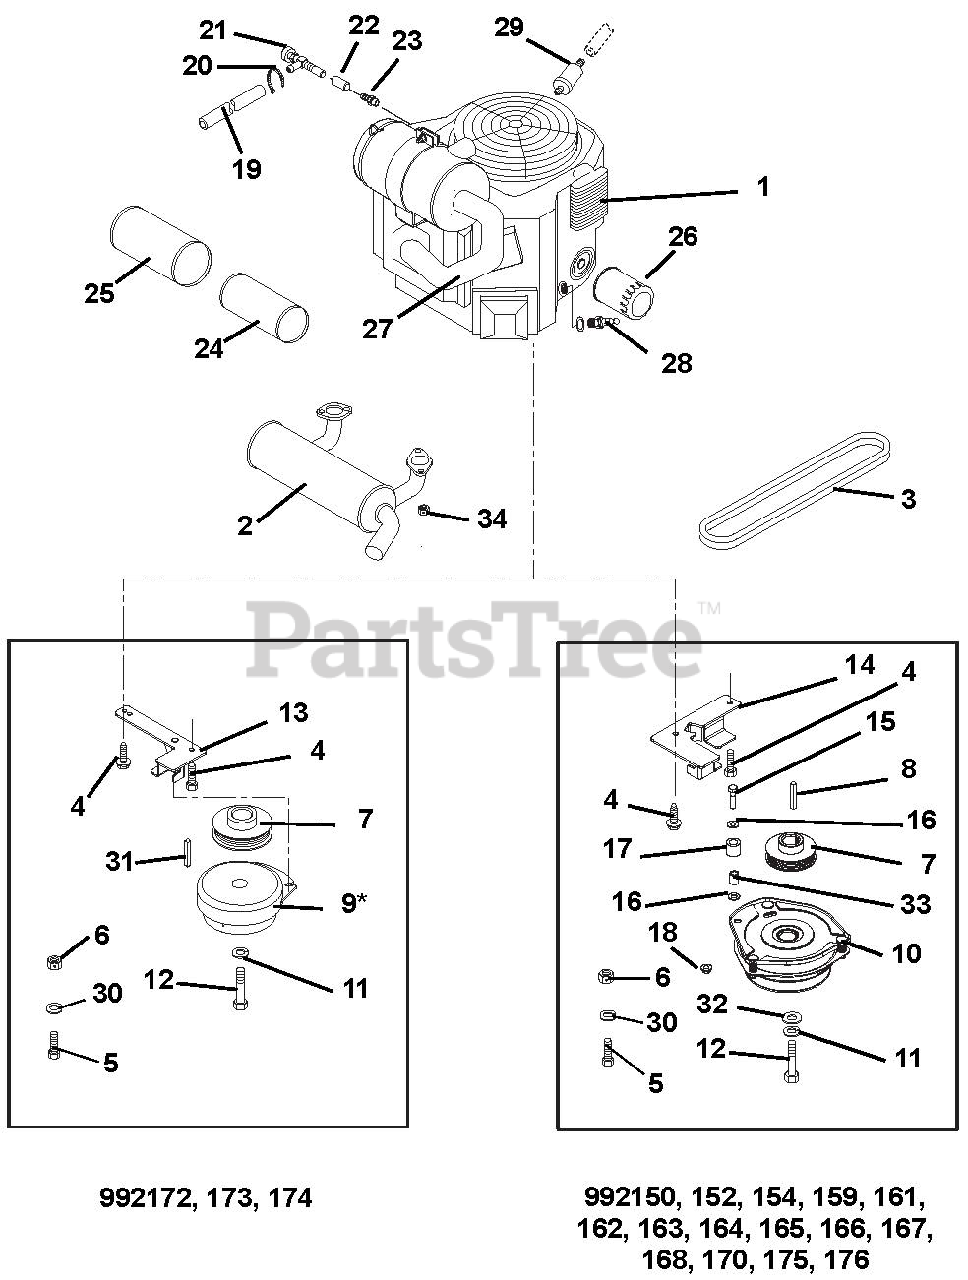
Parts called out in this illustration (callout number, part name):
1	Engine, 26hp Liquid Cooled Kawasaki
1	Engine, 27hp Kohler
1	Engine, 27hp Kawasaki
1	Engine, 25hp Kohler Command
1	Engine, 30hp Kohler Command Pro
1	Engine, 31hp Kawasaki
1	Engine, 27hp Kohler Command
2	Muffler, Kawasaki Vertical
2	Muffler, Kawasaki Liquid Cooled
2	Muffler, Kohler Twin
3	Belt, Poly-V
4	Screw, Tapping Hex Washer Head .38-16 x 1.50
4	Bolt, Hex M8-1.25 x 25 Grade 8
4	Bolt, Hex .38-16 x 1.25 FTH G5 EP30
5	Bolt, Hex .31-18 x 1.75 Grade 5
6	Nut, Locking Top Flange .31-18
7	Sheave, Poly V 1.127 x 3.275
8	Key, Square .25 x 3.50 x .25 SAE
9	Clutch, Electric
10	Clutch, Electric
11	Washer, Locking .44 x .109
12	Bolt, Hex .44-20 x 3.00 Grade 5 YZ EP80
12	Bolt, Hex .44-20 x 1.50 Grade 5 YZ EP80
13	Anchor, Clutch
14	Anchor, Clutch
15	Bolt-Hex .38-16 x 1.50 Grade 5
16	Washer-Flat-Steel .406 x .812 x .065
17	Bumper, Rubber .62 x 1.0 x .88 LG
18	Nut, Locking-Top-Flange .38-16
19	Gas Line, Bulk .25 I.D.
20	Cable Tie LG 5-1/2
21	Drain, 1/2" Drain
22	Adapter, .38 NPTF
23	Nipple, Pipe .375-18 NPTF x 3.00
24	Element, Inner Safety
24	Air Filter
25	Element, Outer Primary
25	Element, Pre-Cleaner
26	Oil Filter
27	Hose, Air Intake
28	Spark Plug
29	Fuel Filter
30	Washer, Locking-EXT.326 x .599 x .031
31	Key, Square .25 x 1 x 0.25
32	Washer, Flat Steel .469 x 2 x .25
33	Bushing, .407 x .625 x .813
34	Nut, Locking, Top M8-1.25
